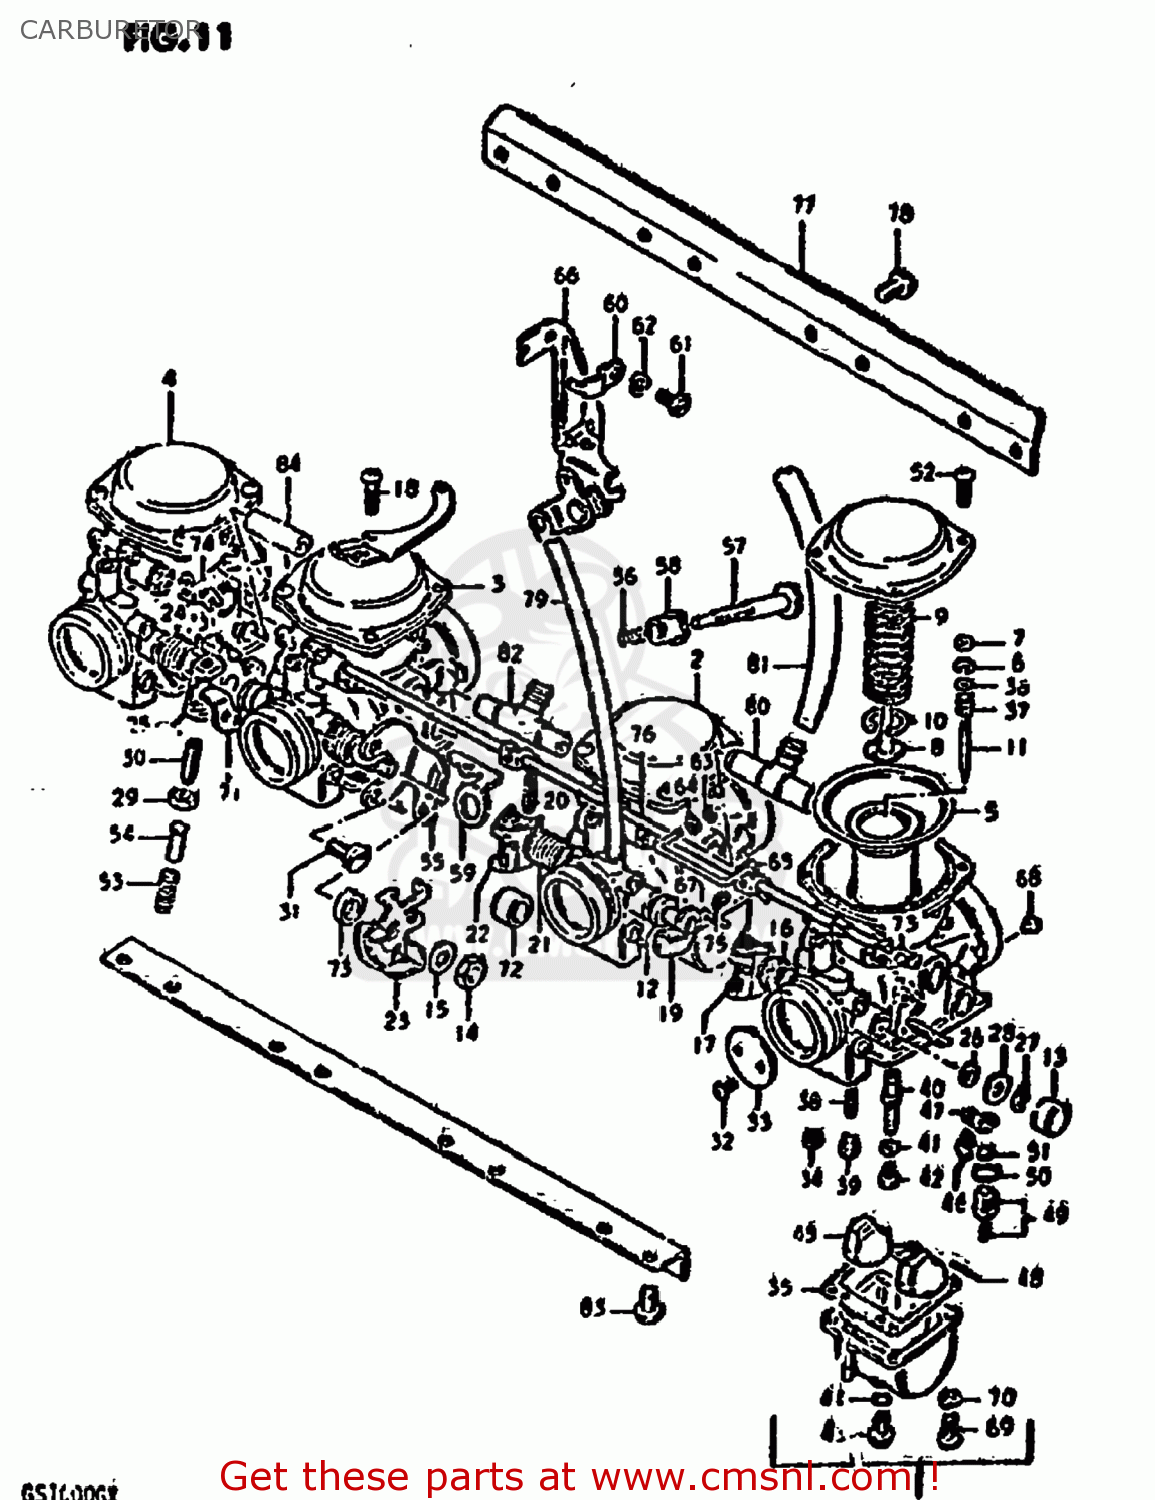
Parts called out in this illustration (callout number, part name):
1	CARBURETOR ASSEMBLY
2	CARBURETOR ASSEMBLY,NO.2
3	CARBURETOR ASSEMBLY
4	CARBURETOR ASSEMBLY
5	DIAPHRAGM ASSEMBLY
6	CLIP,NEEDLE
7	RING
8	HOLDER,GUIDE
9	SPRING
10	E RING
11	NEEDLE JET
12	GASKET
13	CAP
14	NUT
15	WASHER
16	SPRING,THROTTLE SHAFT
17	SHAFT,THROTTLE
18	SCREW
19	SHAFT,THROTTLE
20	PIN,THROTTLE SHAFT
21	SPRING,THROTTLE SHAFT
22	LEVER,THROTTLE SHAFT
23	LEVER ASSEMBLY,THROTTLE
24	SPRING,THROTTLE SHAFT
25	SHAFT,THROTTLE
26	SEAL
27	E RING
28	GASKET,THROTTLE SHAFT (NAS)
29	NUT
30	SCREW
31	SCREW
32	SCREW
33	VALVE,THROTTLE
34	GASKET (NAS)
35	GASKET,FLOAT CHAMBER (NAS)
36	WASHER
37	SPRING
38	JET,PILOT
39	PLUG,NEEDLE JET
40	JET,NEEDLE
41	WASHER,NEEDLE NOZZLE
42	JET,MAIN(115)
43	PLUG,DRAIN
44	GASKET (NAS)
45	FLOAT
46	SCREW
47	PLATE
48	PIN,FLOAT
49	VALVE ASSEMBLY,NEEDLE
50	O RING
51	FILTER
52	SCREW
53	SPRING,THROTTLE SCREW
54	PIN,THROTTLE LEVER
55	BRACKET,THROTTLE ADJUST
56	SPRING
57	SCREW
58	BUSH
59	BRACKET,THROTTLE ADJUST
60	BRACKET,STARTER
61	BOLT
62	LOCK WASHER
63	CAP,LEVER
64	SEAT,SPRING
65	LEVER ASSY
66	BRACKET
67	ROD,STARTER LEVER
68	JET,AIR
69	SCREW
70	LOCK WASHER
71	SHAFT,THROTTLE
72	RING
73	RING
74	LEVER
75	SCREW
76	SHAFT,STARTER
77	BRACKET
78	SCREW
79	HOSE
80	NIPPLE
81	HOSE
82	NIPPLE
83	SCREW 6X12
84	NIPPLE
